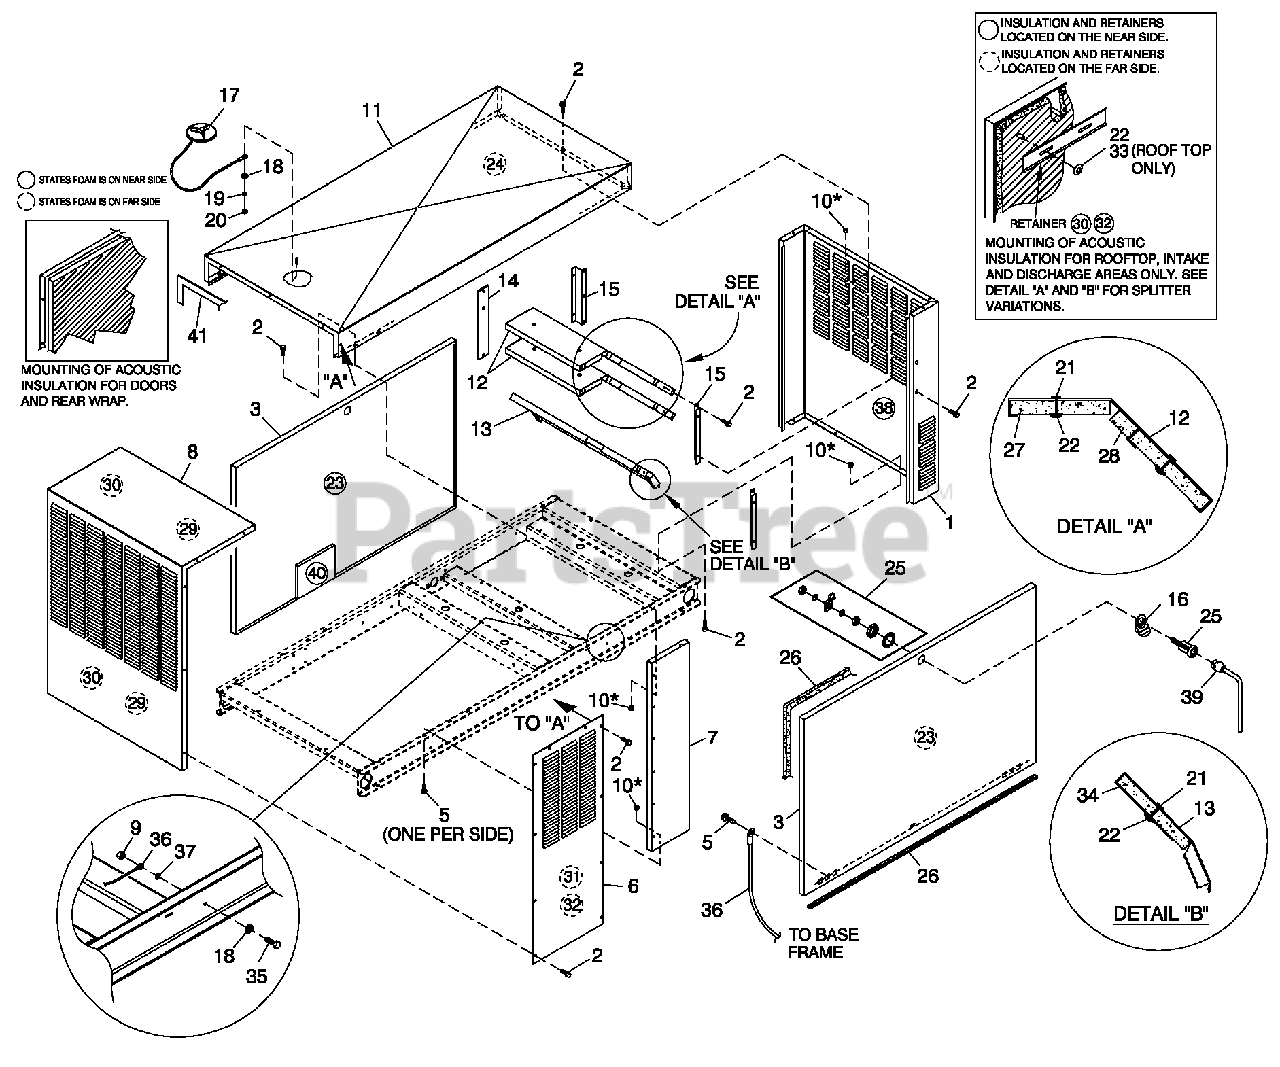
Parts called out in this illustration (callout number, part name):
1	REAR WRAP C2 CPL
2	SCREW THF M6-1 X 16 N WA Z/JS
3	DOORC2
4	RIVET POP.1875 X .450 SS
5	SCREW TH-FRM M6 W/CAP SHKPRF W
6	DISCHARGE DUCT LH & RH SIDE C2
7	FRONT CORNERS C2
8	DISCHARGE CENTER DUCT C2
9	NUT HEX M6X 1.0 G8YEL CHR
10	NUT HEX LOCK M6-1.0 SS NY INS
11	ROOF C2
12	SLITTER C4
13	SPLITTER LOWER C4
14	SPLITTER STINGER C2
15	SUPPORT SPLITTER LH C2
16	TAB PULL
17	ASSEMBLY COVER ACCESS
18	WASHER FLAT 1/4-M6 ZINC
19	WASHER LOCK M6-1/4
20	NUT HEX 1/4-20 STEEL
21	INSULATION RETAINMENT HANGER
22	WASHER SELF LOCKING DOME #4-40
23	INSULATION DOOR C2
24	INSULATION ROOF TOP
25	VISE-ACTION LATCH SLOTTED CIR
26	GASKET EXTRUDED TRIM (328" LG)
27	INSULATION SPLITTER
28	INSULATION SPLITTER
29	INSULATION DUCT
30	RETAINER INSULATION (820)
31	INSULATION DUCT SIDES
32	RETAINER INSULATION (450)
33	WASHER SELF LOCKING DOME #8-32
34	INSULATION LOWER SPLITTER
35	SCREW HHC M6-1.0X 20 G8.8
36	ASSY WIRE 14 AWG 34.8" GRN/YEL
37	WASHER SHAKEPROOF INT 1/4
38	INSULATION REAR WRAP
39	KEY VISE-ACTION LATCH SLOT CIR
40	FOAM 300 X 300 THERMAL ACO (APPLIES TO 4.2L UNITS ONLY)
41	STRIP SEALANT 1/8 X 1 (44.52"LG)
